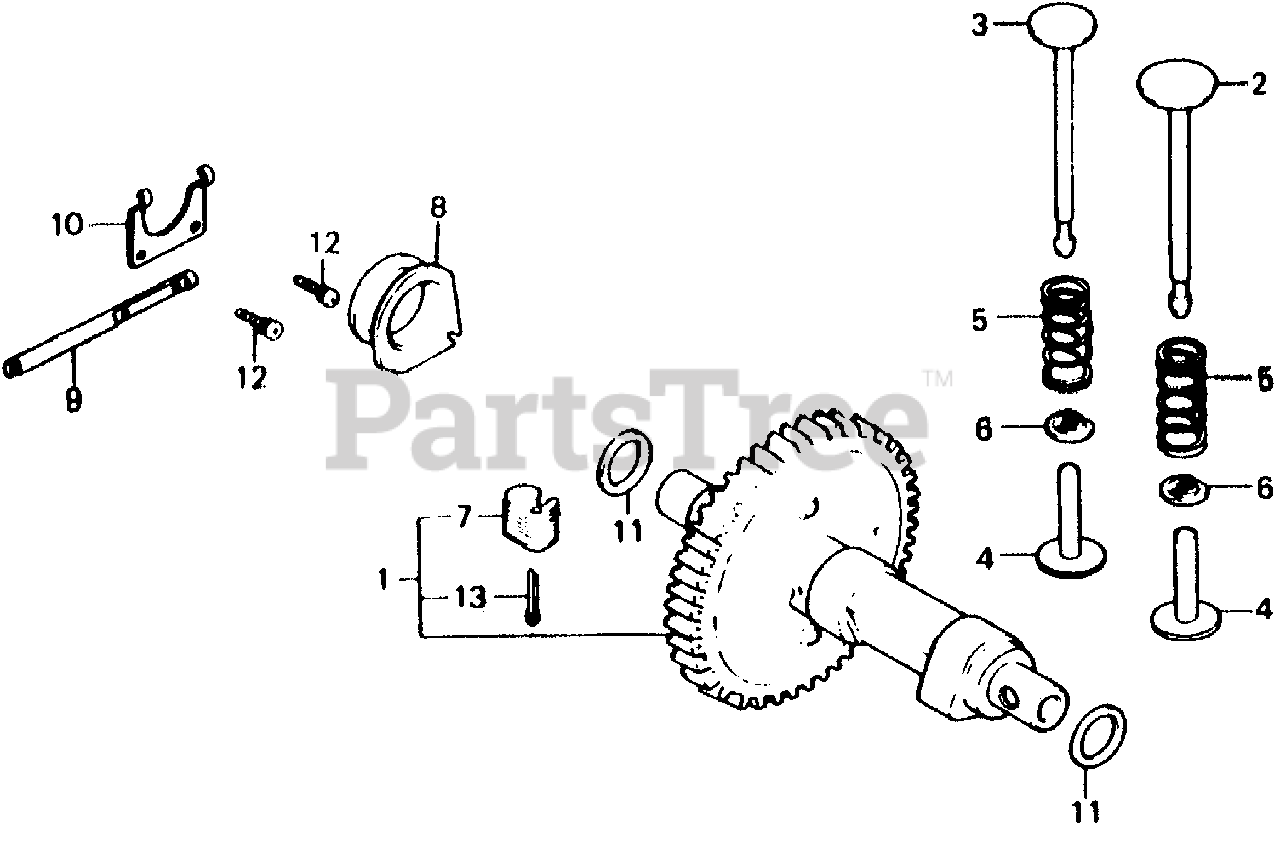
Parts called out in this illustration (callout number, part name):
1	CAMSHAFT ASSY. (NOT AVAILABLE)
2	VALVE, IN.
3	VALVE, EX.
4	LIFTER, VALVE (34.39)
4	LIFTER, VALVE (34.66)
5	SPRING, VALVE
6	RETAINER, VALVE SPRING
7	WEIGHT, GOVERNOR (NOT AVAILABLE)
8	SLIDER, GOVERNOR
9	SHAFT, GOVERNOR ARM
10	FORK, GOVERNOR
11	WASHER, THRUST (18MM)
12	SCREW, PAN (3X6)
13	PIN, COTTER (3.0X45)
